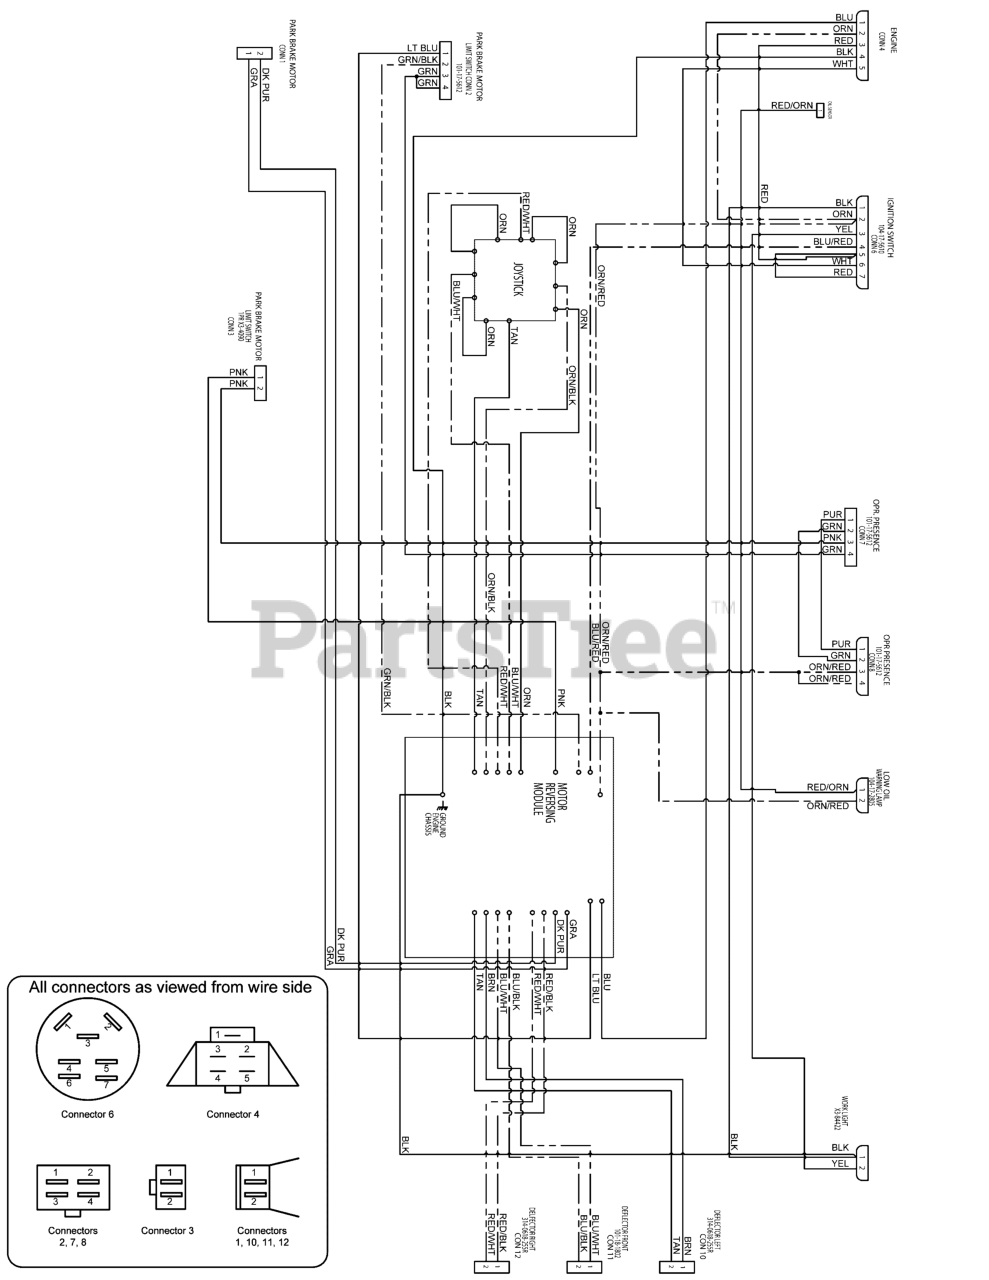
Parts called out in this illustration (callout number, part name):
1	HARNESS, Wiring
2	HARNESS, WIRING
3	HARNESS, WIRING
4	HARNESS, WIRING
5	HARNESS, Wiring
